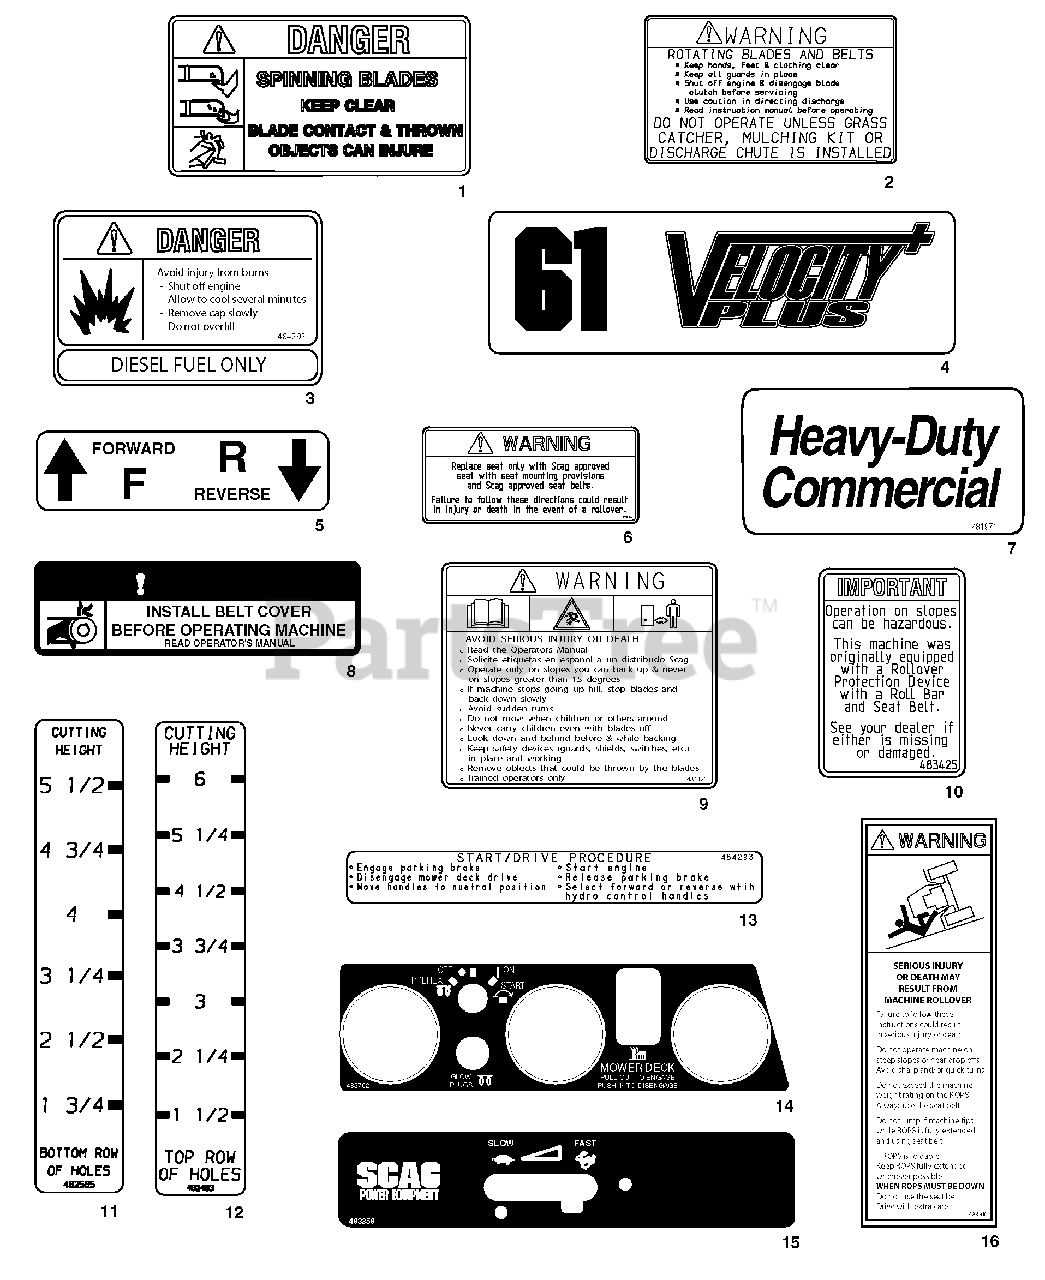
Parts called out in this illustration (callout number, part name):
1	Decal, Danger-Spinning Blades
2	Decal, Warning-Rotating Blades
3	Decal, Fuel Tank
4	Decal, 61" Velocity Plus
6	Decal, 72" Velocity Plus
6	Decal, Seat Replacement
7	Decal, Traction Control
7	Decal, Heavy Duty Commercial
8	Decal, Belt Cover
9	Decal, Warning
10	Decal, ROPS
11	Decal, Cutting Height - Lower
12	Decal, Cutting Height - Upper
13	Decal, Start/Drive Procedure
14	Decal, Instrument Panel - Upper
15	Decal, Instrument Panel - Lower
16	Decal, ROPS Warning
